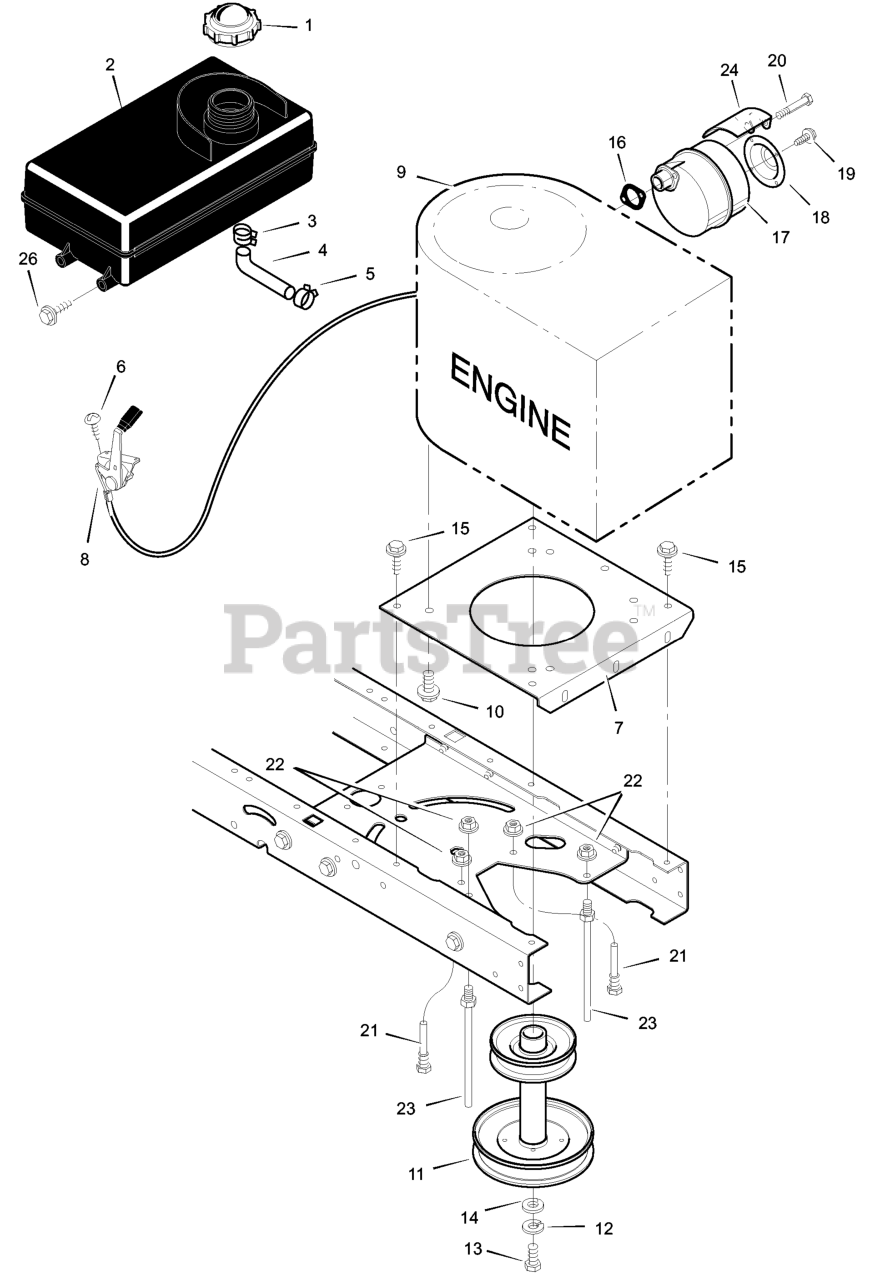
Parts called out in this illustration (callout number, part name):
1	Fuel Cap
2	TANK, Fuel 1.4 Gal.
3	Hose Clamp
4	Fuel Line (Must cut to length)
5	Hose Clamp
7	Plate, Engine
8	Throttle Control
9	Engine *
10	Bolt, Engine Mount
11	STACK PULLEY ASSEMBLY
12	Lockwasher
13	Bolt, Hex
16	GASKET, Exhaust
17	Muffler
18	Deflector, Muffler
20	Bolt, Hex
21	Guide, Belt
22	Nut, Flange
23	Guide, Belt
24	Shield, Heat
